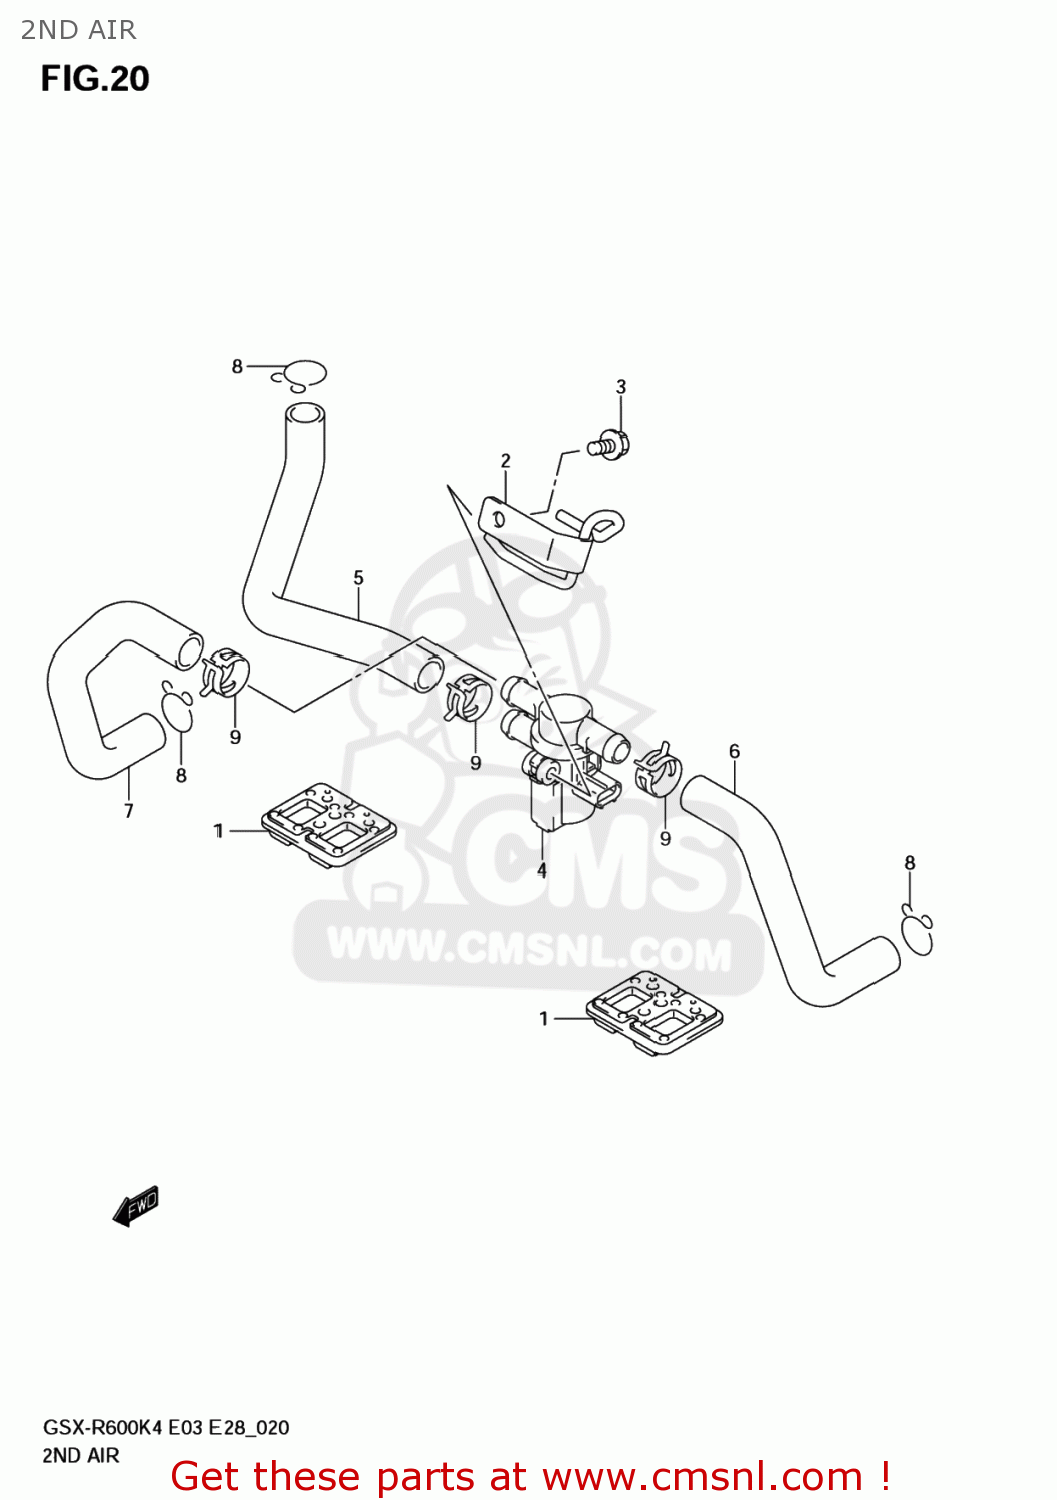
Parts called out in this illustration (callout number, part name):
1	VALVE ASSY,2ND AIR REED
2	BRACKET,2ND AIR VALVE
3	BOLT
4	VALVE ASSY,AIR CUT
5	HOSE,2ND AIR CLEANER
6	HOSE,2ND AIR VALVE,L
7	HOSE,2ND AIR VALVE,R
8	CLIP
9	CLIP
